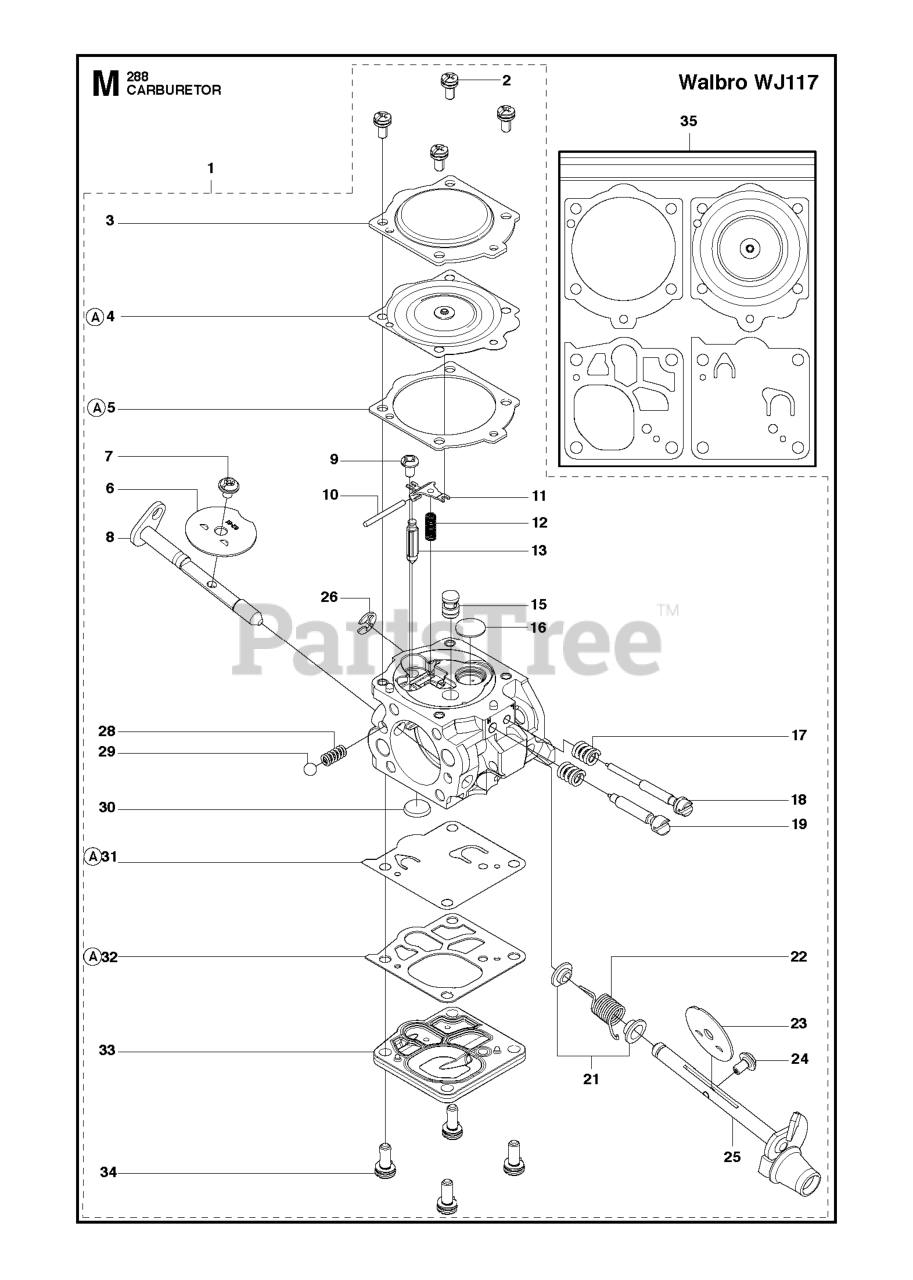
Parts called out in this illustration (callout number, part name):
1	CARBURETOR
3	DIAPHRAM COVER
4	DIAPHRAGM ASSY
6	CHOKE FLAP
13	INLET NEEDLE
16	WELCH PLUG
17	SPRING/COMPRESSION
18	NEEDLE
19	SCREW
23	THROTTLE VALVE (W34-185)
26	E CLIP
30	FUEL INLET SCREEN
31	DIAPHRAM PUMP
34	SCREW W/ WASHER
35	GASKET KIT
